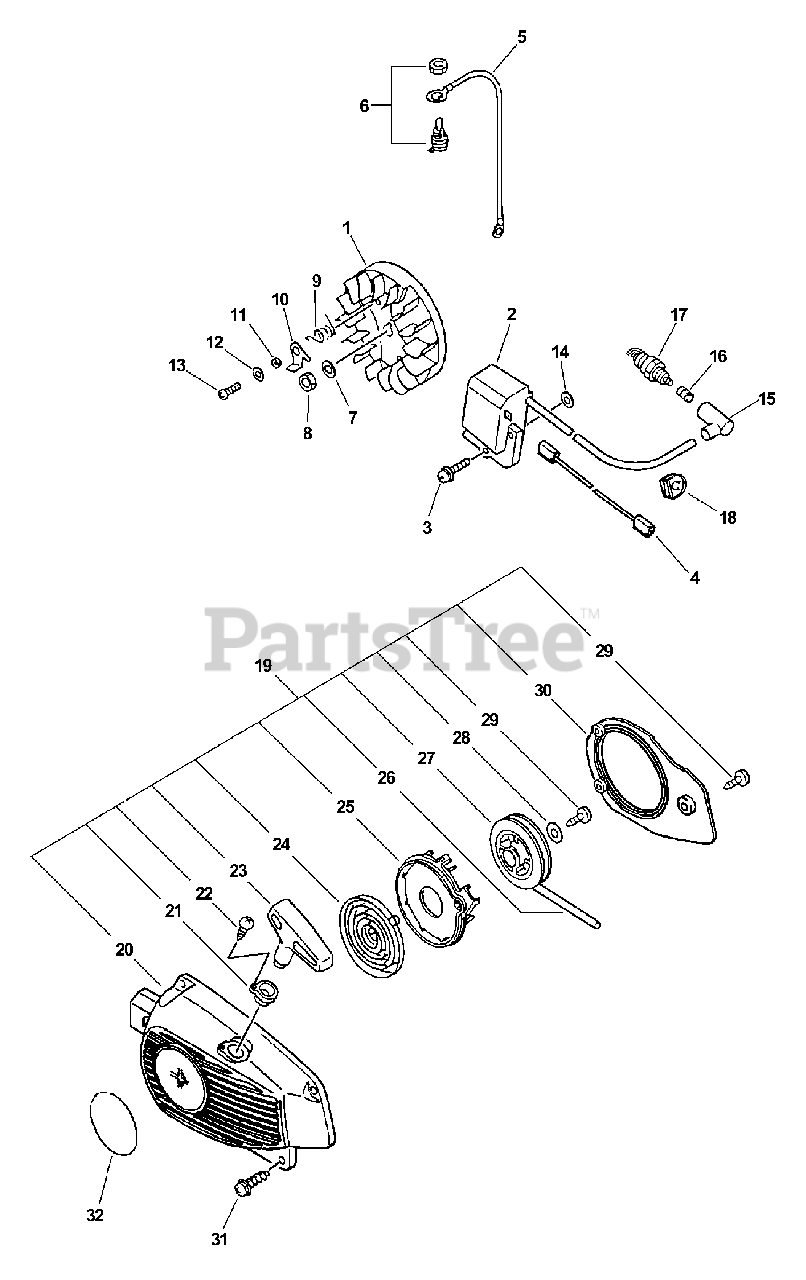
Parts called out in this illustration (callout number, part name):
1	FLYWHEEL
2	COIL, IGNITION
3	SCREW 5×20
3	SCREW 5×22
4	LEAD - IGNITION L= 95
5	LEAD - GROUND L= 100
6	SWITCH, ON-OFF
7	WASHER 8.5×16×1.2
8	NUT M8
9	SPRING, TORSION
10	PAWL, STARTER
11	SPACER 5.2×8×2.1
12	WASHER 5.5×12×0.8
13	SCREW 5×12
14	WASHER 5.2×12×3
15	CAP, SPARK PLUG
16	TERMINAL, SPARK PLUG
17	SPARK PLUG - BPM7A
17	SPARK PLUG - BPMR7A
18	GROMMET
19	STARTER ASSY
20	CASE, STARTER
21	GUIDE, ROPE
22	SCREW 3×14
23	GRIP, STARTER
24	SPRING, RECOIL
25	PLATE, STARTER
26	ROPE, STARTER 3.0×850
27	REEL, ROPE
28	WASHER 4.1×15.5×1T
29	SCREW 4×14
31	SCREW 4×16
32	LABEL, ECHO
